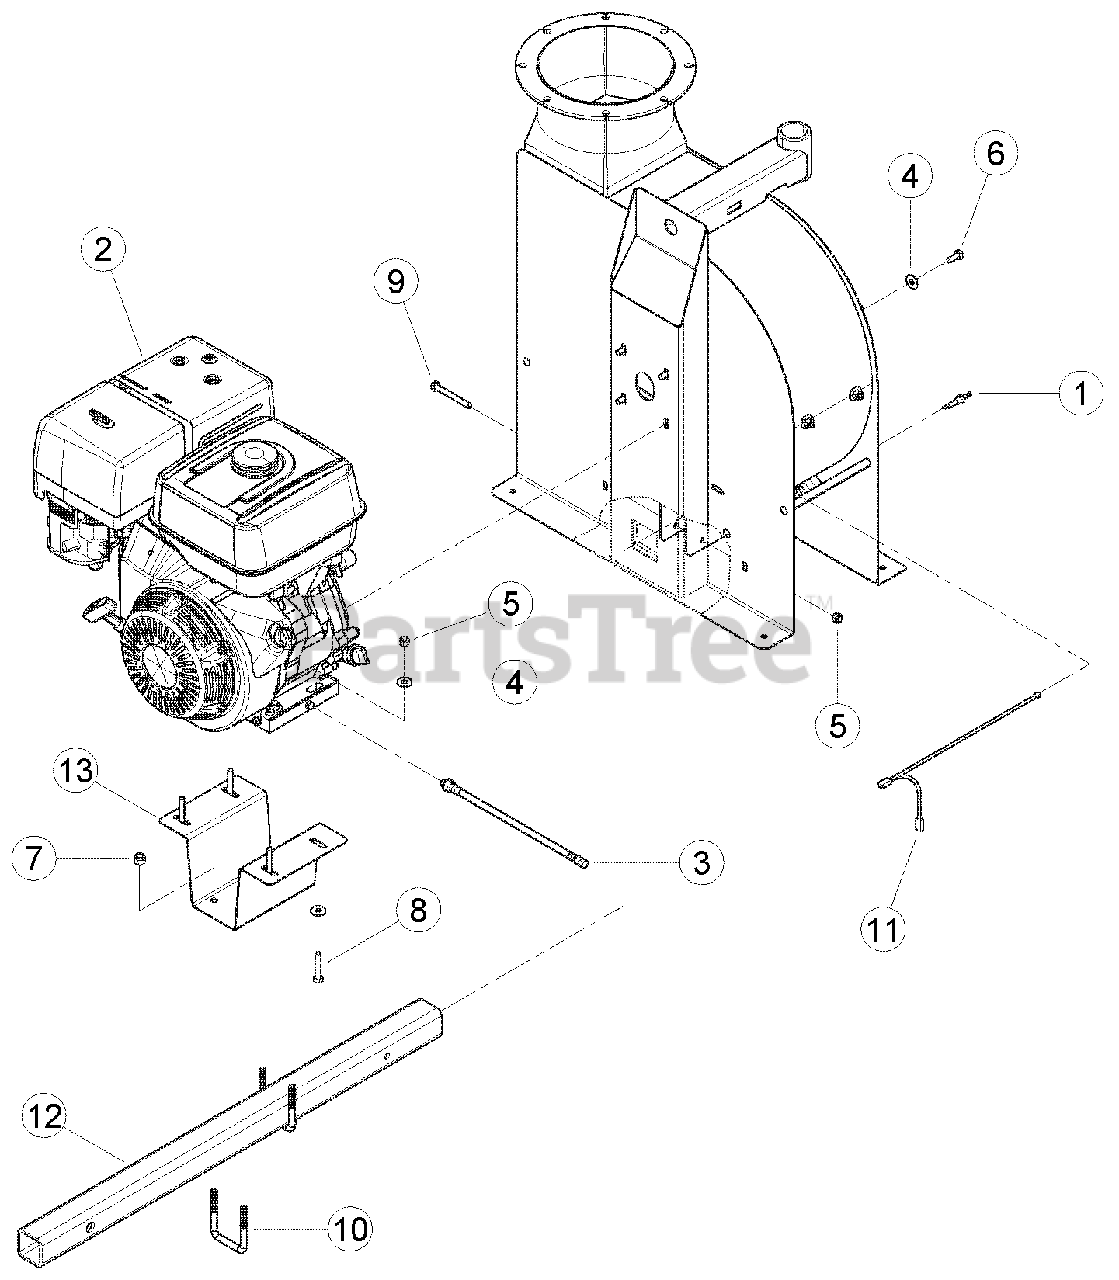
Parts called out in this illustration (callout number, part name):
1	SWITCH, ENGINE KILL
2	ENGINE, B&S V-TWIN 570CC (FOR SERVICE SEE ENGINE OWNER'S MANUAL OR YOUR NEAREST AUTHORIZED BRIGGS & STRATTON ENGINE DEALER)
3	HOSE ASSY, CRANKCASE DRAIN
4	WASHER, 5/16 FLAT ZP
5	NUT, 5/16 NE NYLOCK ZP
6	BOLT, 5/16-24 X 3/4 HHCS GR5 ZP
7	NUT, 3/8 NE NYLOCK ZP
8	BOLT, 5/16-18 X 1-3/4 HCS GR5 ZP
9	BOLT, 5/16 X 2-3/4 HCPS GR5
10	U-BOLT, 3/8-16 X 2.06 X 3.00 SQ ZP
11	WIRE ASSY', ENGINE KILL
12	TUBE, HITCH
13	MOUNT, ENGINE SUPPORT
